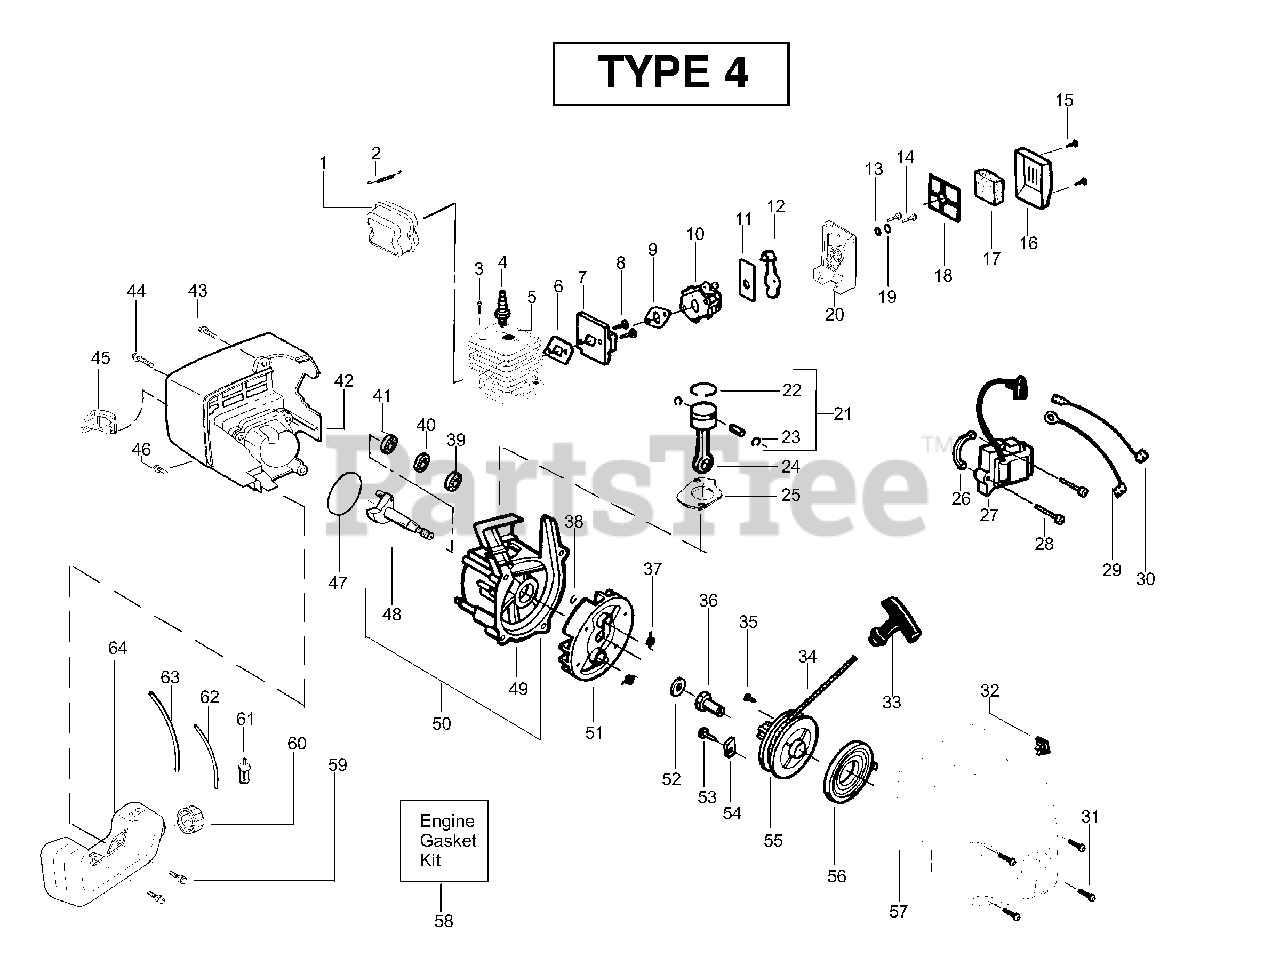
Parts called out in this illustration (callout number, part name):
1	Kit - Muffler
2	Muffler Spring
3	Screw-Cylinder
4	Spark Plug (RCJ-6Y)
5	Kit - Cylinder
6	Gasket-Cyl/Carb. (kit)
7	Adaptor-carb.
9	Gasket-Carb. (kit)
10	Kit-Carb. (WA226)
11	Plate-Choke Mounting
12	Lever-Choke
16	Cover-Air Box
17	Foam-Air Filter
18	Plate-Air Filter Support
19	Spacer-Choke
21	Kit - Piston
22	Piston Ring
23	Retainer-Piston Pin
24	Assy-Connecting Rod
25	Gasket-Cylinder (kit)
26	Spacer-Module
27	Ignition Module
29	Assy-Ground Wire
30	Assy-Leadwire
31	Screw
32	Kit-Switch
33	Handle-Starter
34	Kit - Rope
36	Coupling-Drive
37	Spring-Starter Dog
38	Retain. Ring-C'shaft
39	Bearing-Outer
40	Seal-C'case
41	Bearing-Inner
44	Screw
45	Guard-Muffler
47	O-Ring-C'case(kit)
48	Assy-Crankshaft
49	Assy-Crankcase
50	Assy-C'case & C'shaft
51	Assy-Flywheel
52	Washer-Flat
54	Retainer-Can
55	Kit-Starter Pulley
56	Spring-Starter
57	Assy-Fan Housing
58	Kit-Engine Gasket
59	Retainer-Tank
60	Assy-Fuel Cap
61	Assy-Fuel Pickup
62	Kit-Fuel Line
63	Kit-Fuel Line
64	Assy-Fuel Tank
